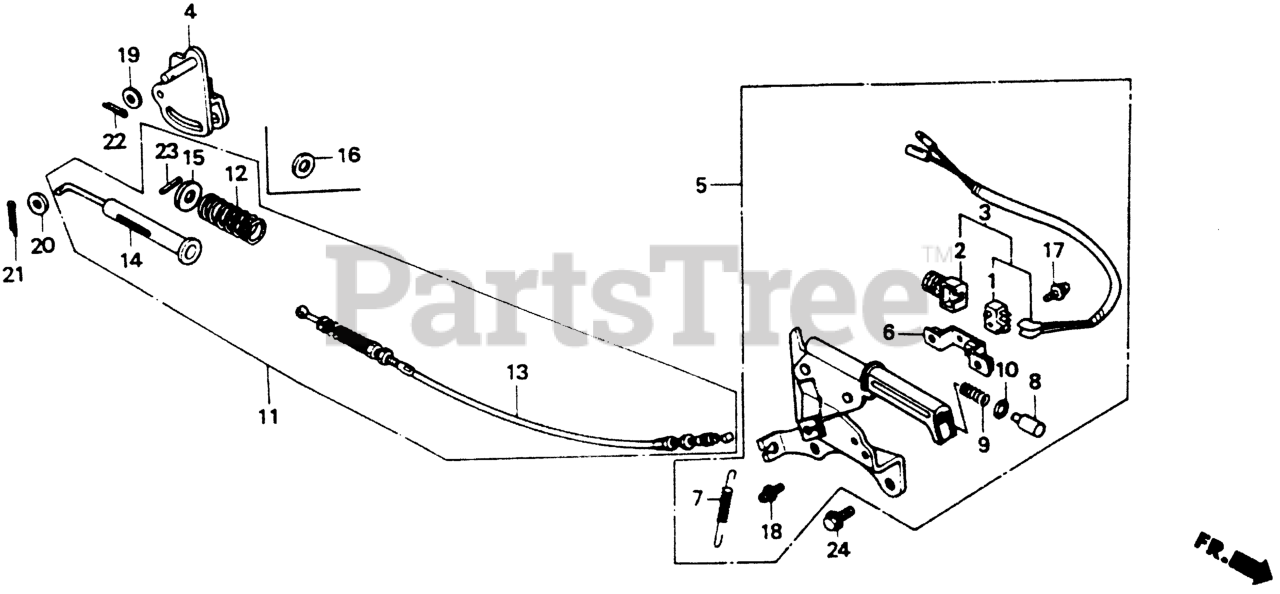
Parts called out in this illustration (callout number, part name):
1	SWITCH ASSY., CLUTCH
2	COVER, SWITCH
3	SWITCH ASSY., PARKING BRAKE
4	ARM, BRAKE (NOT AVAILABLE)
5	LEVER ASSY., PARKING BRAKE
6	STAY, PARKING BRAKE SWITCH
8	KNOB, PARKING BRAKE PUSH ROD
9	SPRING, PUSH ROD
10	O-RING, PARKING BRAKE LEVER
11	PIPE ASSY., RR. BRAKE (NOT AVAILABLE)
12	SPRING, PARKING BRAKE LOAD SETTING
13	CABLE, PARKING BRAKE (NOT AVAILABLE)
14	PIPE, RR. BRAKE
15	WASHER, BRAKE SPRING SETTING
17	SCREW-WASHER (4X14)
18	SCREW-WASHER (5X12)
19	WASHER, PLAIN (10MM)
20	WASHER, PLAIN (5MM)
21	PIN, COTTER (2.0X15)
22	PIN, COTTER (2.5MM)
23	PIN, SPRING (6X25)
24	BOLT, FLANGE (8X16)
